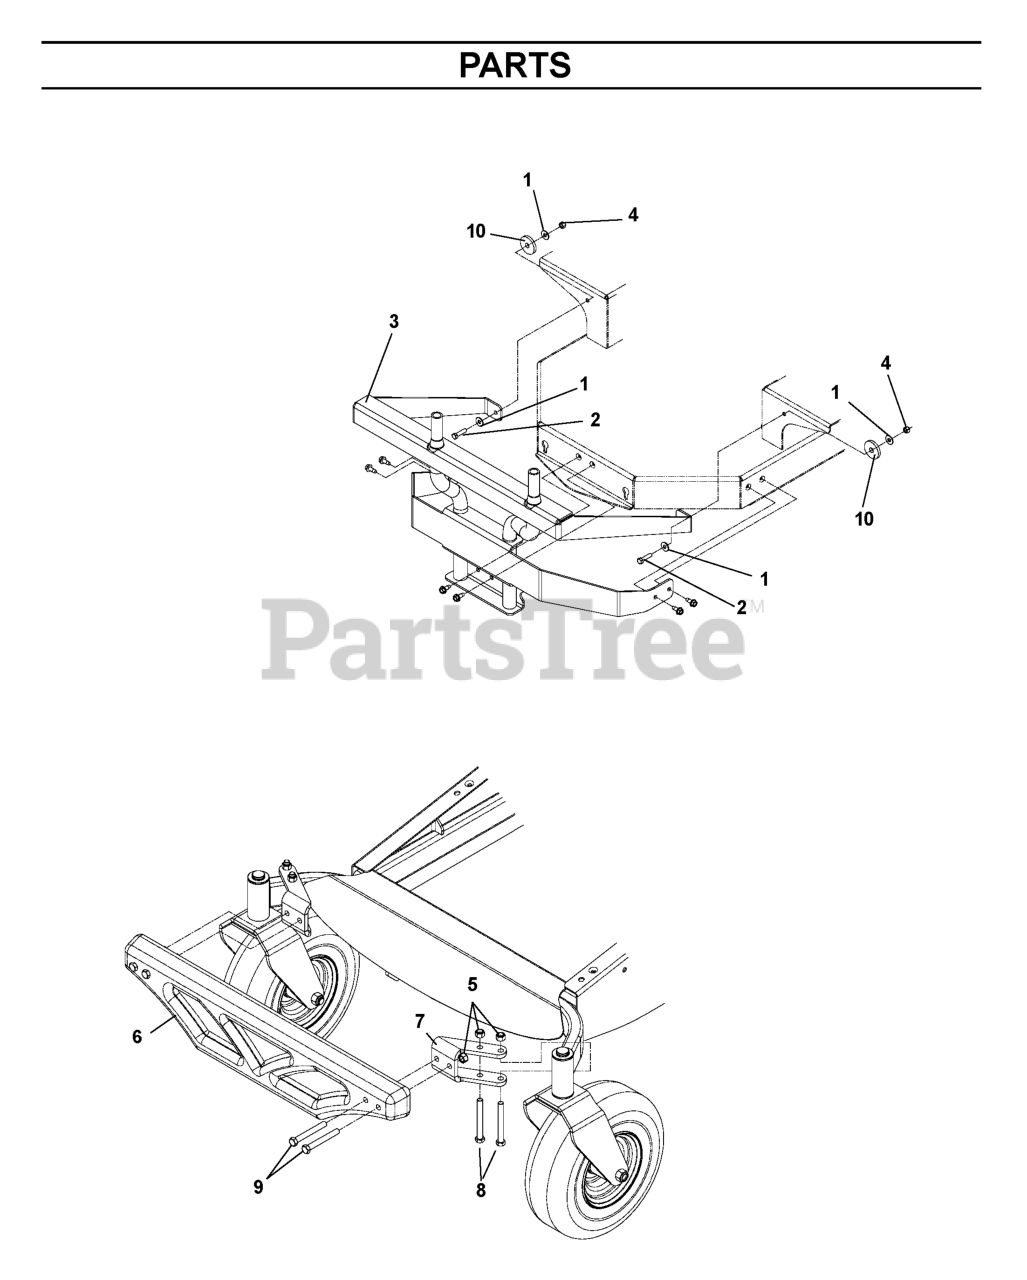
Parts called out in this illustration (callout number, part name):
1	WASHER 5/16 FLAT
2	HCS 5/16C X 1 1/4
4	NUT 5/16 NYLOC
5	NUT 3/8-16 NYLOC
6	CAST WEIGHT
7	WEIGHT BRACKET, BLACK
8	HCS 3/8-16 X 3-1/4 GR5 ZD
9	HCS 3/8C X 3
10	SPINDLE WASHER
